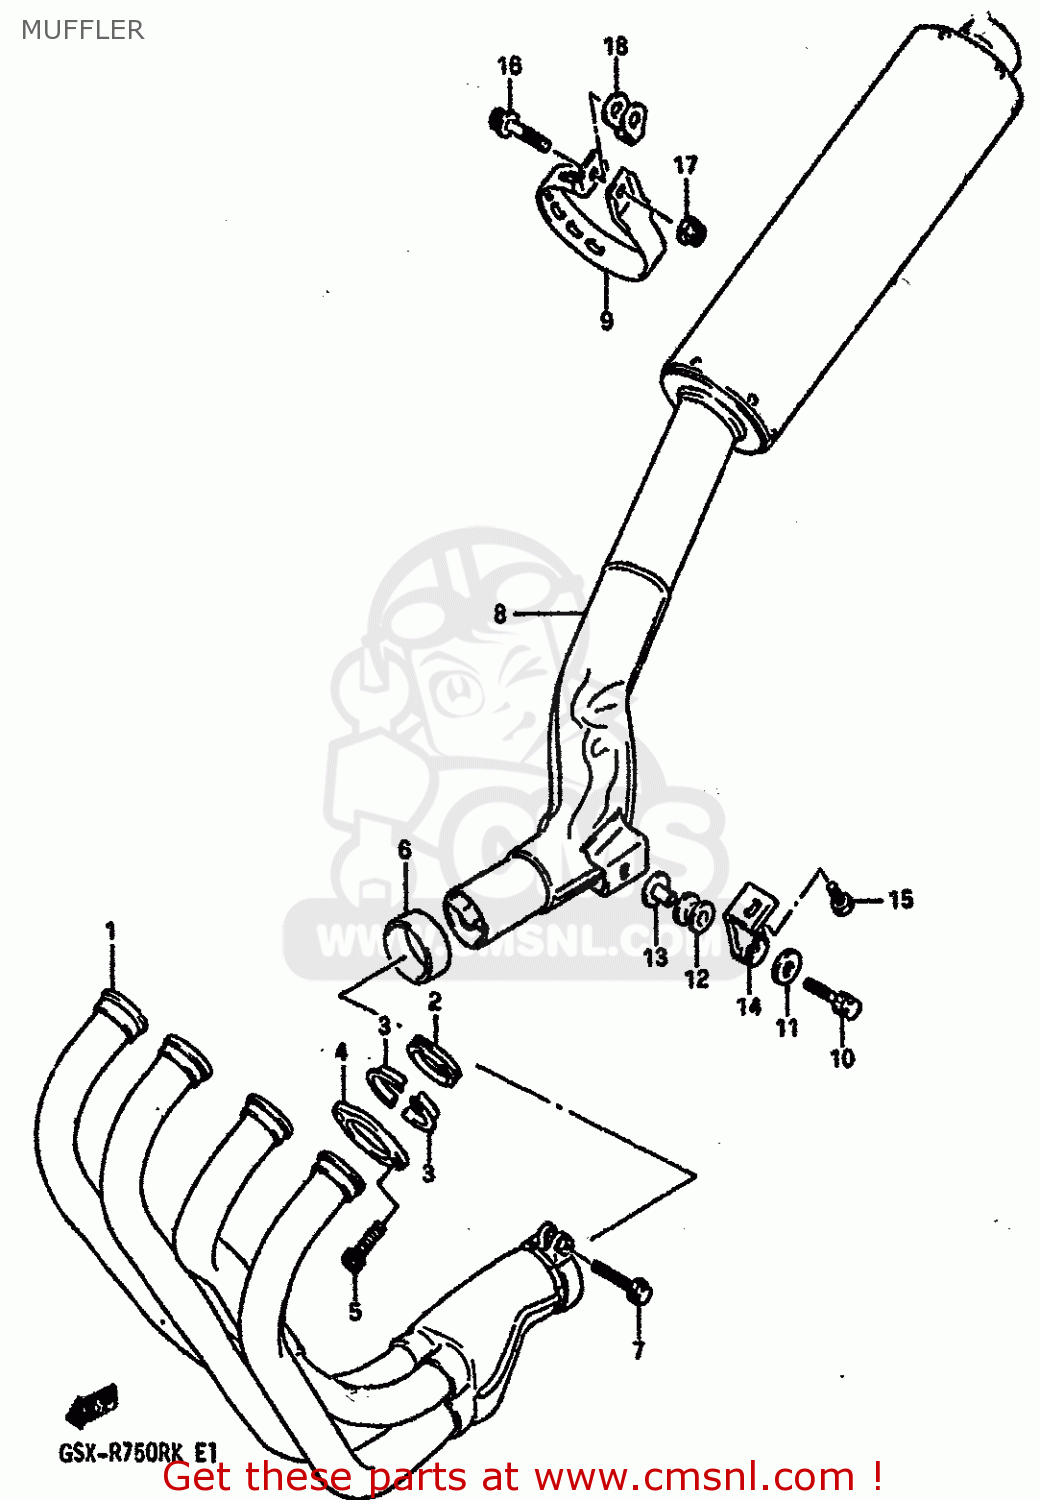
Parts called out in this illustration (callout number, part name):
1	EXHAUST ASSY
2	GASKET,EXHAUST (NAS)
3	PLATE,EXHAUST PIPE
4	CLAMP,EXHAUST PIPE
5	BOLT
6	CONNECTOR,MUFFLER
7	BOLT (8X40)
8	BODY,MUFFLER
9	BRACKET,MUFFLER
10	BOLT 8X35
11	WASHER
12	CUSHION
13	SPACER(8.6X12X18.5)
14	DAMPER,FRONT
15	BOLT(8X20)
16	BOLT
17	NUT
18	WASHER,MUFFLER SUPPORT
